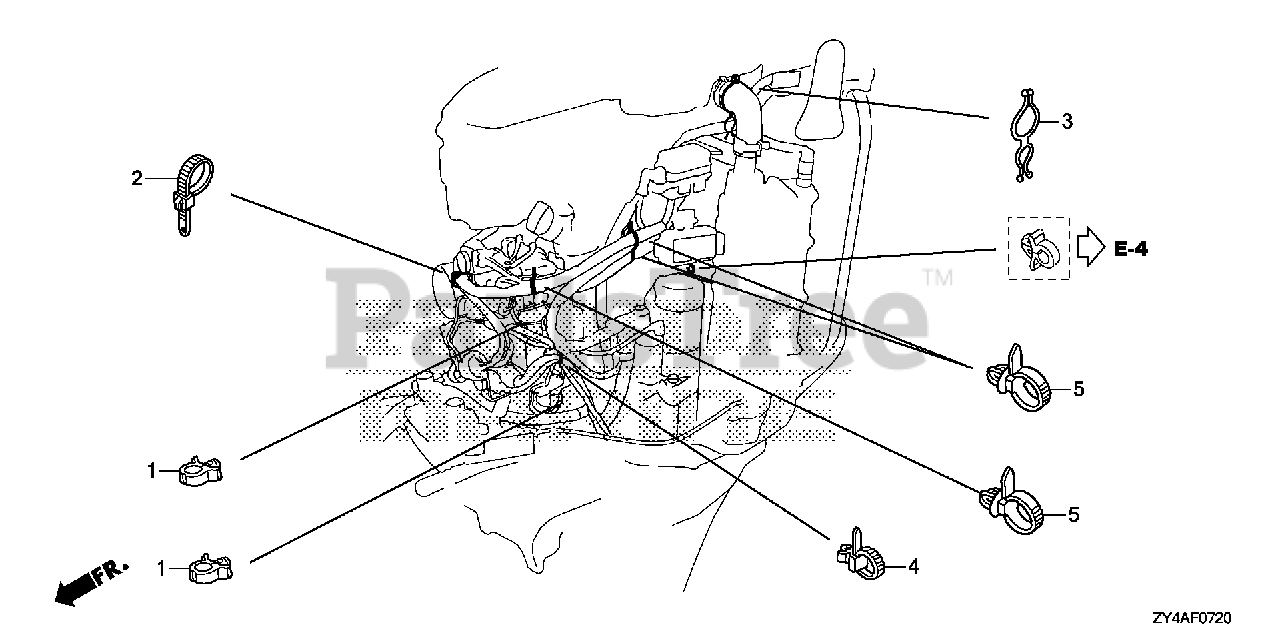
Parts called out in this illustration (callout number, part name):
1	CLIP, BRAKE PIPE (A)
2	TIE, CABLE
3	CLIP B, HARNESS
4	STRAP, CABLE (118MM) (BLACK)
5	CLIP, HARNESS BAND (145MM) (BLACK)
